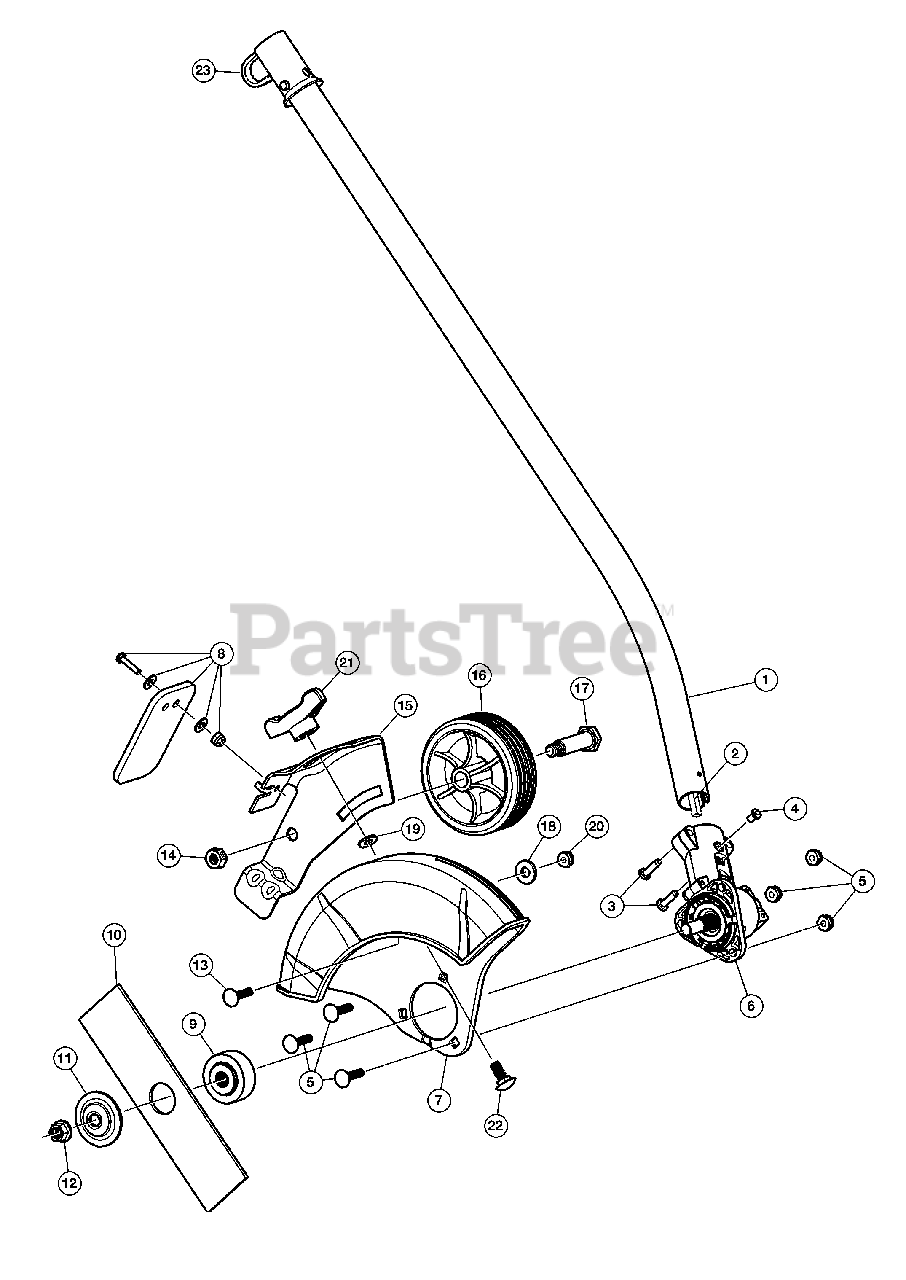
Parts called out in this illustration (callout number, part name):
1	Boom Assembly
2	Drive Shaft
3	Boom Mounting Hardware
4	Anti-Rotation Screw
5	Guard Mounting Hardware
6	Gearbox Assembly
7	Blade Guard
8	Defl ector w/Hardware
9	Spacer
10	Blade
11	Blade Clamp Washer
12	Blade Retainer Nut
13	Wheel Bracket Mounting Bolt
14	Nut
15	Edger Guide
17	Shoulder Bolt
19	Washer
21	Edger Guide Knob
23	Hanger
